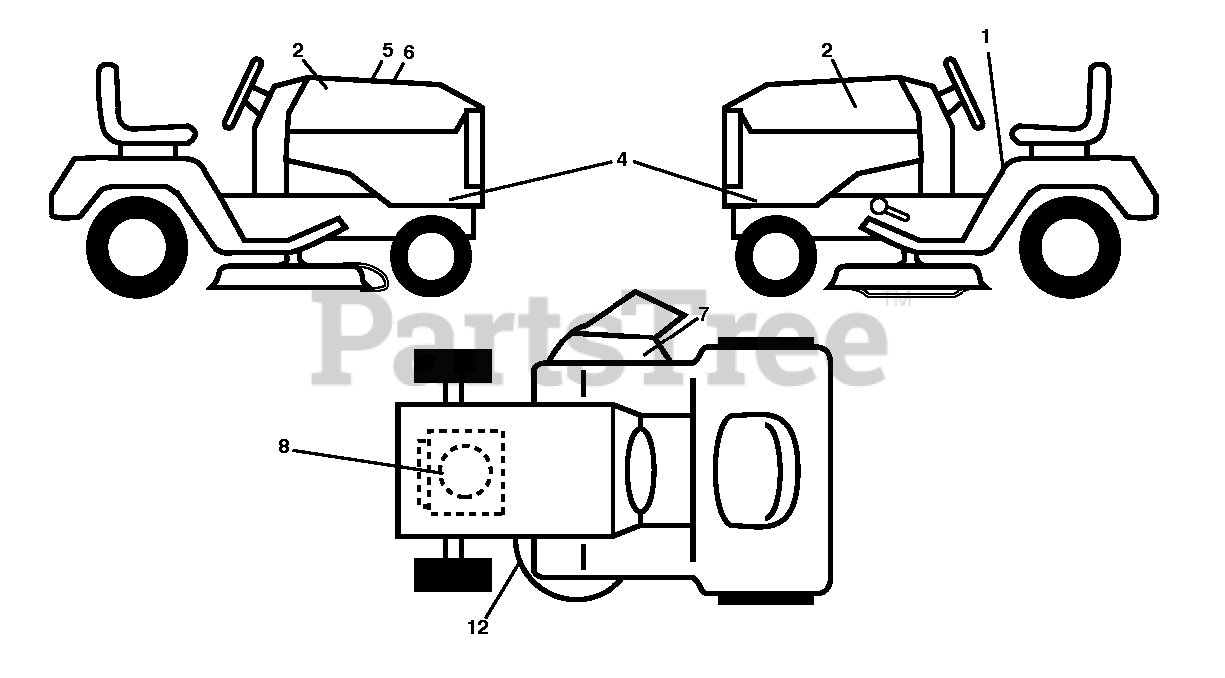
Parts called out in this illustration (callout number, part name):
1	DECAL.FENDER.WARNING.ENGLISH
2	DECAL.BADGE.170MM.TEXTLOGO.
4	DECAL TRACTOR SIDE PANEL DECAL
5	DECAL.WARNING.CUST.RESP.E85.
6	DECAL RPL.K46.46C.B+S M33
7	DECAL, DECK DEFLECTOR, WARNING
8	DECAL.ENG.BS.18.5INTK.381713
12	DECAL.V-BELT.SCH.42/46"MEC/ELE
